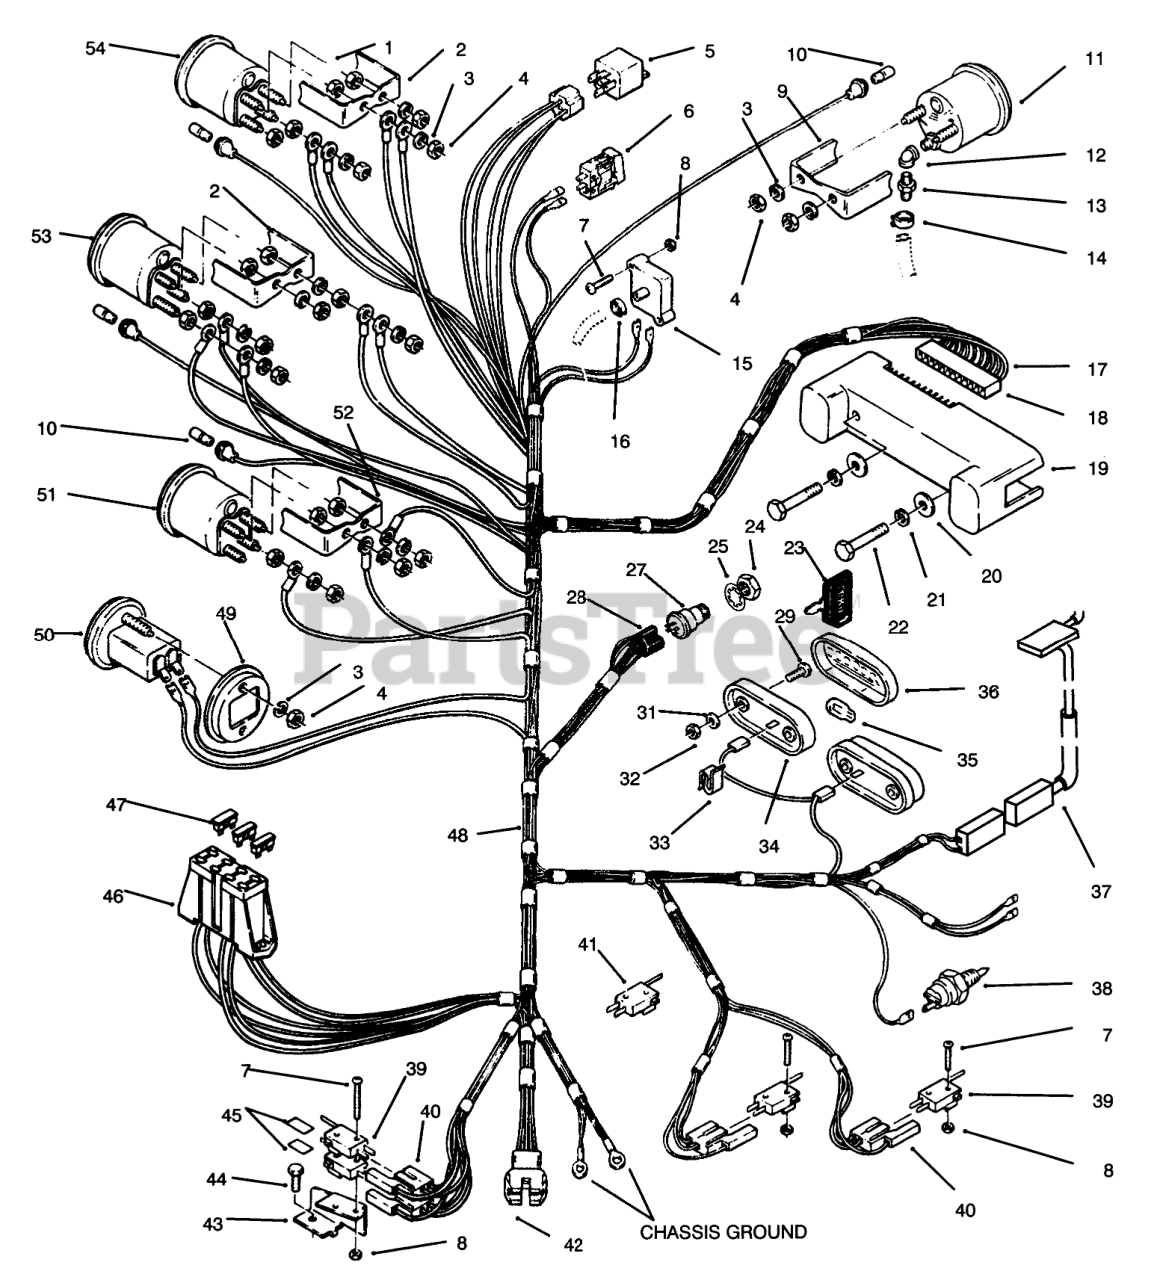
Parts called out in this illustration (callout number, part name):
2	CLAMP-MOUNTING
3	WASHER-LOCK
4	NUT-HEX
5	RELAY
6	Light Switch
7	Screw
8	NUT HEX 4-40 ELAST
9	Bracket-Mounting
10	LAMP-MINIATURE GE 53X
11	Gauge-Vacuum (Incl. Ref. #3-4 & 9)
12	ELBOW
13	FITTING STRAIGHT
14	Clamp
15	SENSOR-AIR CLEANER
16	CLAMP-HOSE 5/16"
17	Terminal
18	Connector-Male
19	CIRCUIT-BRD 8 LIGHT
20	WASHER-FLAT
21	WASHER-LOCK
22	SCREW
23	KEY-IGNITION
25	WASHER-LOCK
27	Switch-Ignition (Incl. Ref. #24-25)
28	CONNECTOR-5 WAY-SERV
29	SCREW-PPH
31	WASHER-LOCK, INT
32	NUT-LOCK, NI
33	SPEED CLIP
34	BASE-TAIL LIGHT
35	LIGHT BULB
36	LENS-TAIL LIGHT
37	SWITCH-SEAT
38	SENSOR-HYDRO OIL HOT
39	SWITCH
40	CONNECTOR BODY
41	SWITCH - CLUTCH
42	9-CIRCUIT CAP
43	Support-Switch
44	Bolt
45	BARRIER - SWITCH
46	FUSE-HOLDER 4 WAY
47	FUSE-10 AMP
48	WIRING-HARNESS & DIA
49	CLAMP-HOUR METER
50	Hourmeter (Incl. Ref. #3-4 & 49)
51	Tachometer (Incl. Ref. #1, 3-4 & 52)
52	BRACKET - GAUGE MOUNT
53	Gauge-Fuel (Incl. Ref. #2-4)
54	Voltmeter (Incl. Ref. #2-4)
